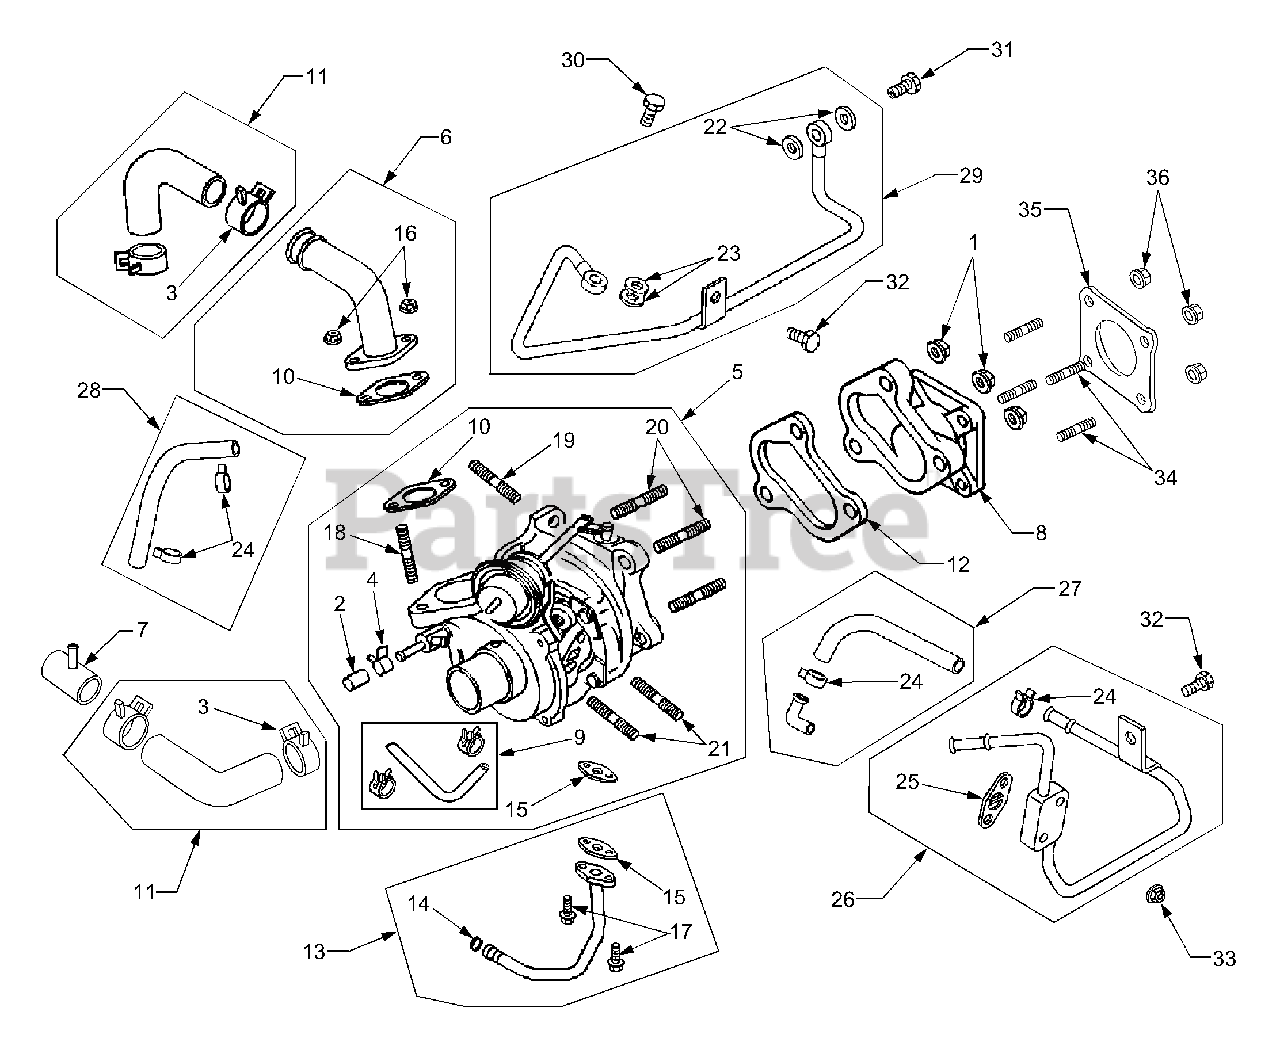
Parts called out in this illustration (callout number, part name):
3	Clamp, Hose
4	Clamp, Hose
5	Charger, Turbo
6	Pipe, Air Inlet
7	Adapter, Air Cleaner
8	Adapter, Muffler
9	Hose, Vacuum
10	Gasket, Air Inlet Pipe
11	Hose/Clamp Assembly
12	Gasket, Muffler Adapter
13	Pipe, Oil Outlet
14	Seal, O Ring (Oil Outler Pipe)
15	Gasket, Oil Outlet
16	Nut, Hex (Air Inlet Pipe)
17	Screw (Oil Outlet Pipe)
18	Stud, Turbo Charger
19	Stud, Turbo Charger
20	Stud, Turbo Charger
21	Stud, Turbo Charger
22	Washer, Sealing (Oil Inlet Pipe)
23	Washer, Sealing (Oil Inlet Pipe)
24	Clamp, Hose
25	Gasket, Water Pipe
26	Pipe, Water
27	Line, Water
28	Line, Water
29	Pipe, Oil Inlet
30	Screw (Oil Inlet Pipe)
31	Screw (Oil Inlet Pipe)
33	Nut, Hex (Water Pipe)
34	Stud, Muffler
35	Gasket, Muffler
36	Nut, Hex (Muffler)
